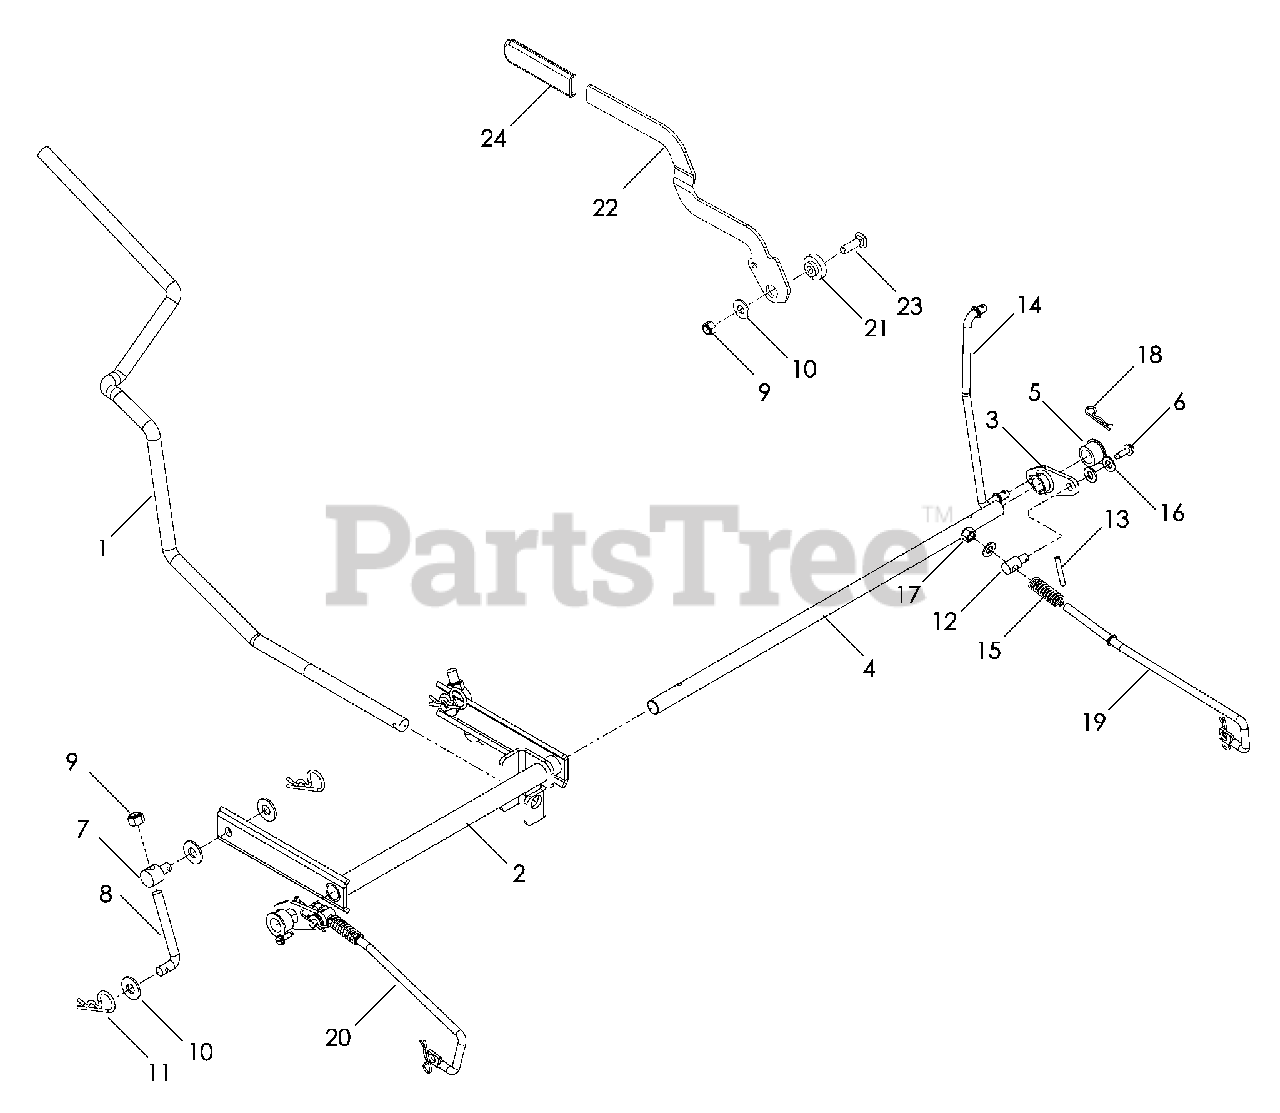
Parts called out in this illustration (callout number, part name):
1	HANDLE, LIFT
2	SHAFT, LIFT
3	BELLCRANK, BRAKE
4	ROD, BRAKE
5	BUSHING, PLASTIC
6	SCREW 10-24 x 5/8" WSH HD
7	SWIVEL
8	L-ROD 31/8"
9	NUT 3/8-16 HEX NYLOC
10	WASHER 3/8 FLAT STD
11	HAIRPIN
12	SWIVEL, BRAKE
13	ROLL PIN 3/16"
14	LINKAGE, UPPER
15	SPRING
16	WASHER 5/16 SAE FLAT
17	NUT 5/16-18 HEX NYLOC
18	HAIRPIN COTTER
19	LINKAGE, BRAKE RT
20	LINKAGE, BRAKE LT
21	PIVOT, BRAKE ARM
22	HANDLE, BRAKE
23	RHSNB 3/8-16 x 1¼
24	GRIP, BRAKE HANDLE
